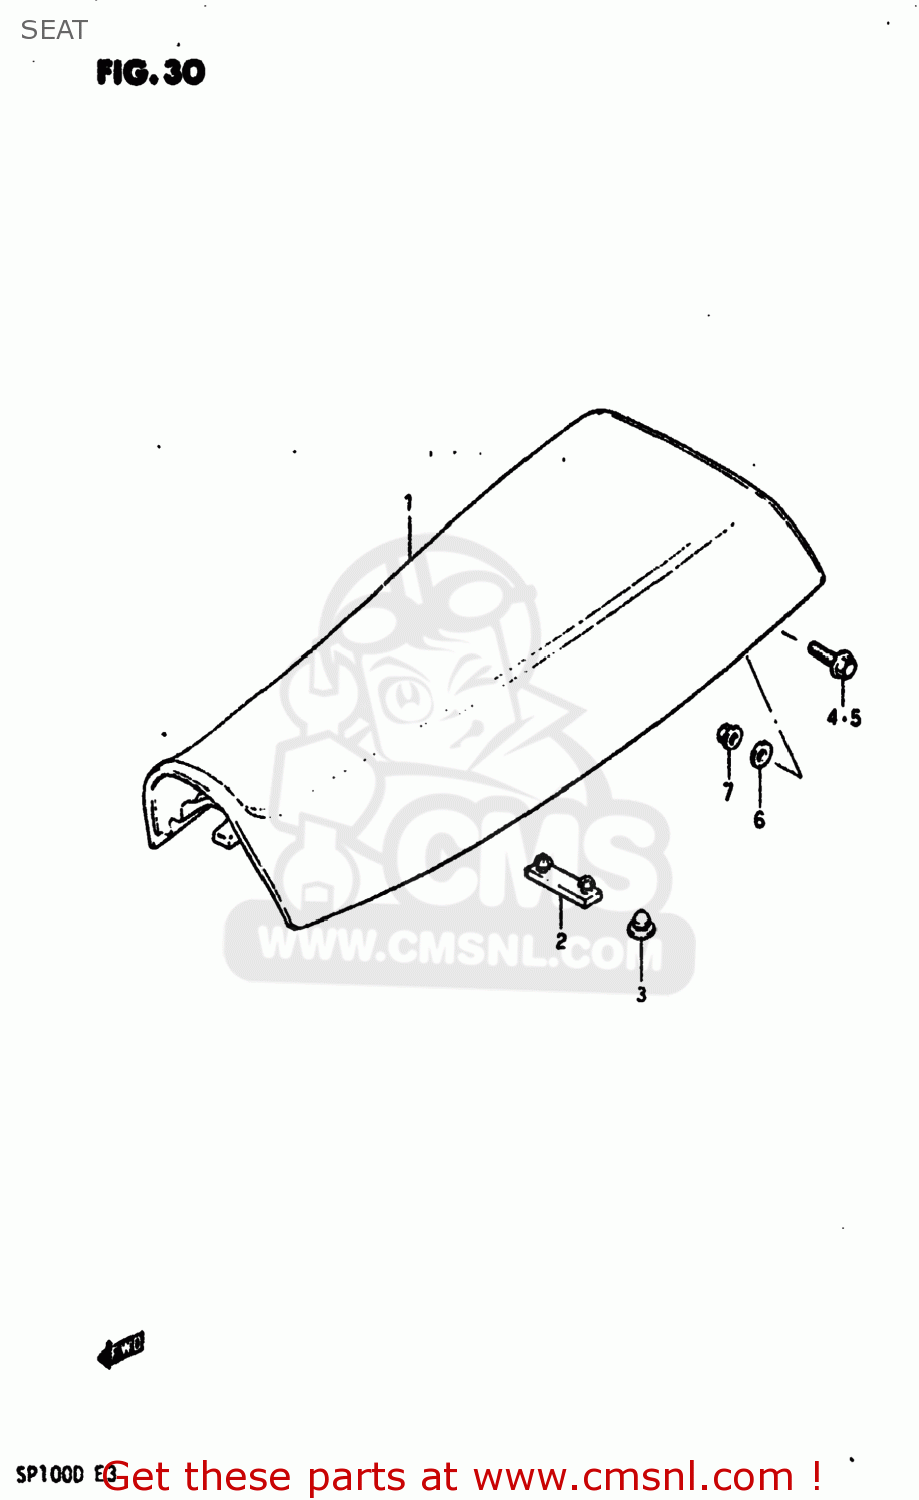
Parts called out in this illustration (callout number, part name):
1	SEAT ASSEMBLY
2	CUSHION
3	CUSHION
4	BOLT, LOWER
5	BOLT
6	WASHER(8.5X23X1.2)
7	NUT M8
